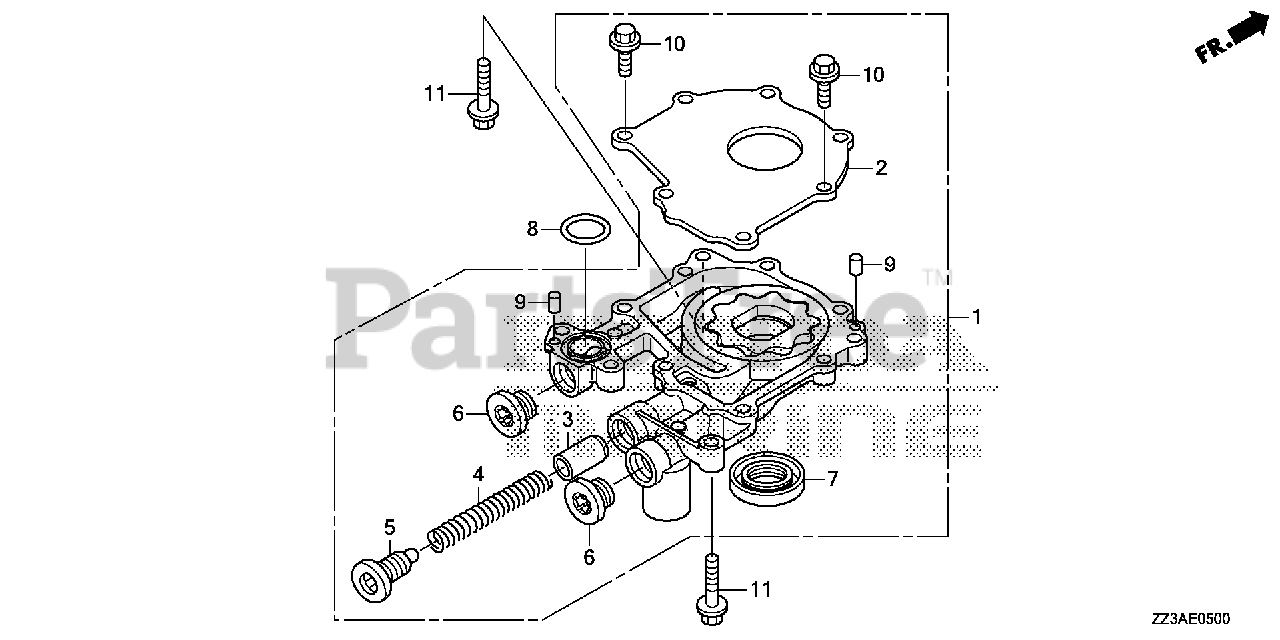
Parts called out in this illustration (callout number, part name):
1	PUMP ASSY., OIL
2	COVER, OIL PUMP
3	VALVE, RELIEF
4	SPRING, RELIEF VALVE
5	BOLT, SEALING (14MM)
6	BOLT, SEALING (14MM)
7	OIL SEAL (31X46X7) (NOK)
8	O-RING (21.2X2.4) (ARAI)
9	ROLLER (5X8)
10	BOLT, FLANGE (6X14)
11	BOLT, FLANGE (6X25)
